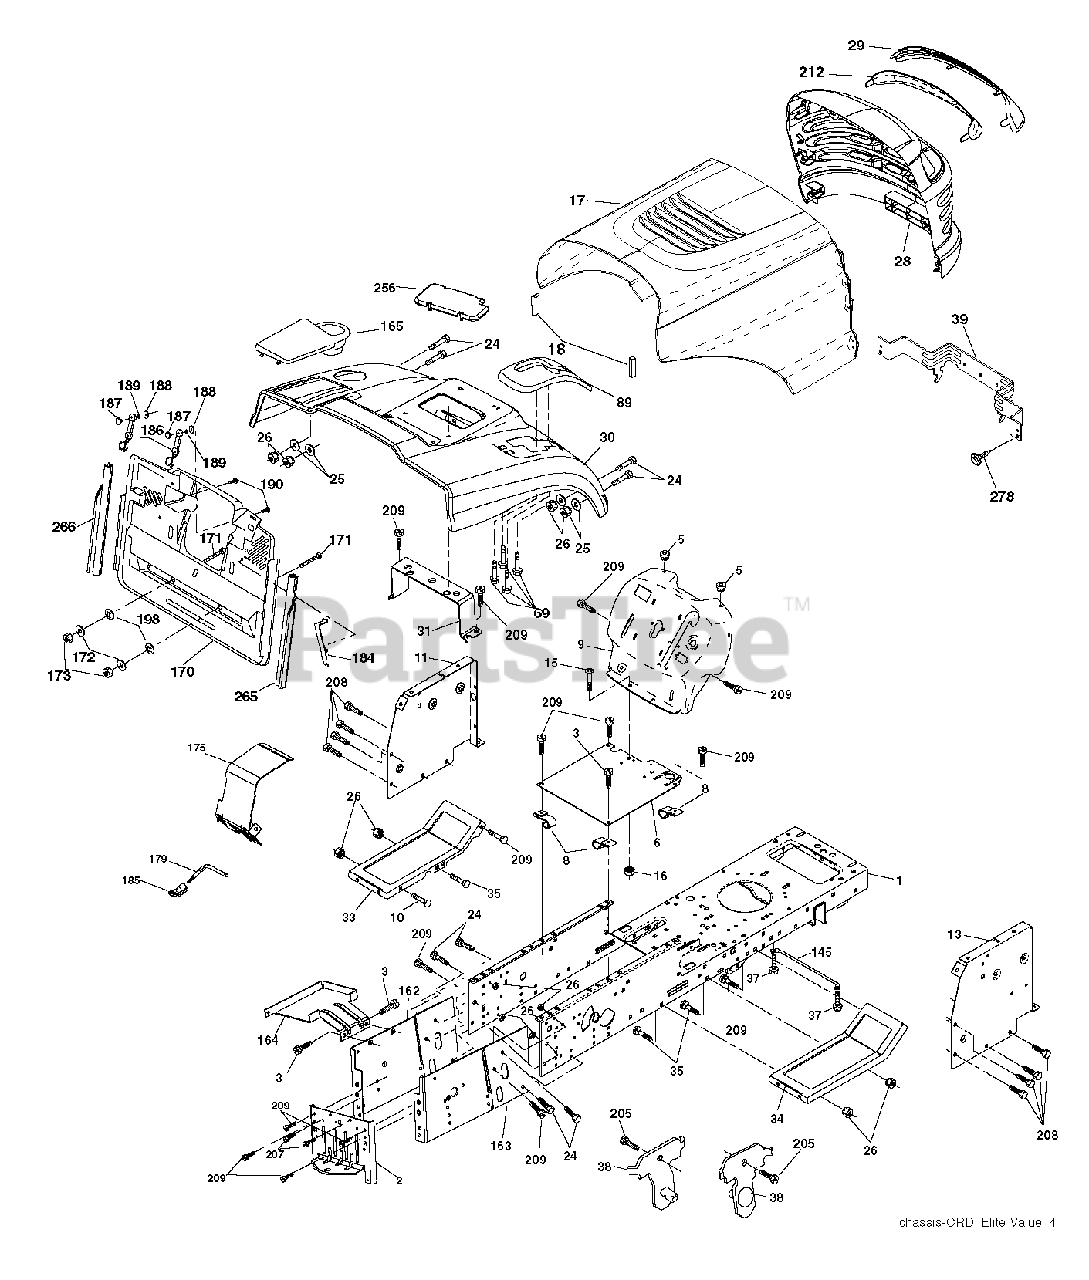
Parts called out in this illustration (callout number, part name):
1	CHASSIS
5	BUMPER.RUBBER.HOOD
8	CLIP,INSULATOR
9	FENDER LT SH
11	PANEL.DASH.LH.LTX
17	BOOT.STEERING.STEALTH
18	BUMPER.HOOD.LARGE.1.75"
25	WASHER
26	NUT
28	HOOD.PNT.STL.ELITE
29	LENS GRILL VALUE BAR LT CLEAR
30	FENDER.PNT.CRD.MS-417.2005
31	BRACKET SUPPORT FENDER
33	FOOTREST.RH.VGT
37	SCREW LT
39	BRACKET PIVOT
69	SCREW.HI-LO.CONSOLE
89	CONSOLE.CRD.AUTO.BLACK
145	ROD.PIVOT.HOOD
164	SUPPORT
171	BOLT
184	BRACKET.ACTUATOR.BAGGER.SRD
185	KNOB.BRAKE.PARKING.ROD
186	LATCH ASSY
187	WELDNUT
189	LOCKWASHER
205	SCREW LT
207	SCREW, 5/16-18 X 1/2
208	SCREW 3/8-16X1/2
209	SCREW, 3/8-16X3/4
278	SCREW.#10 X 0.750.BOS (2 2)
